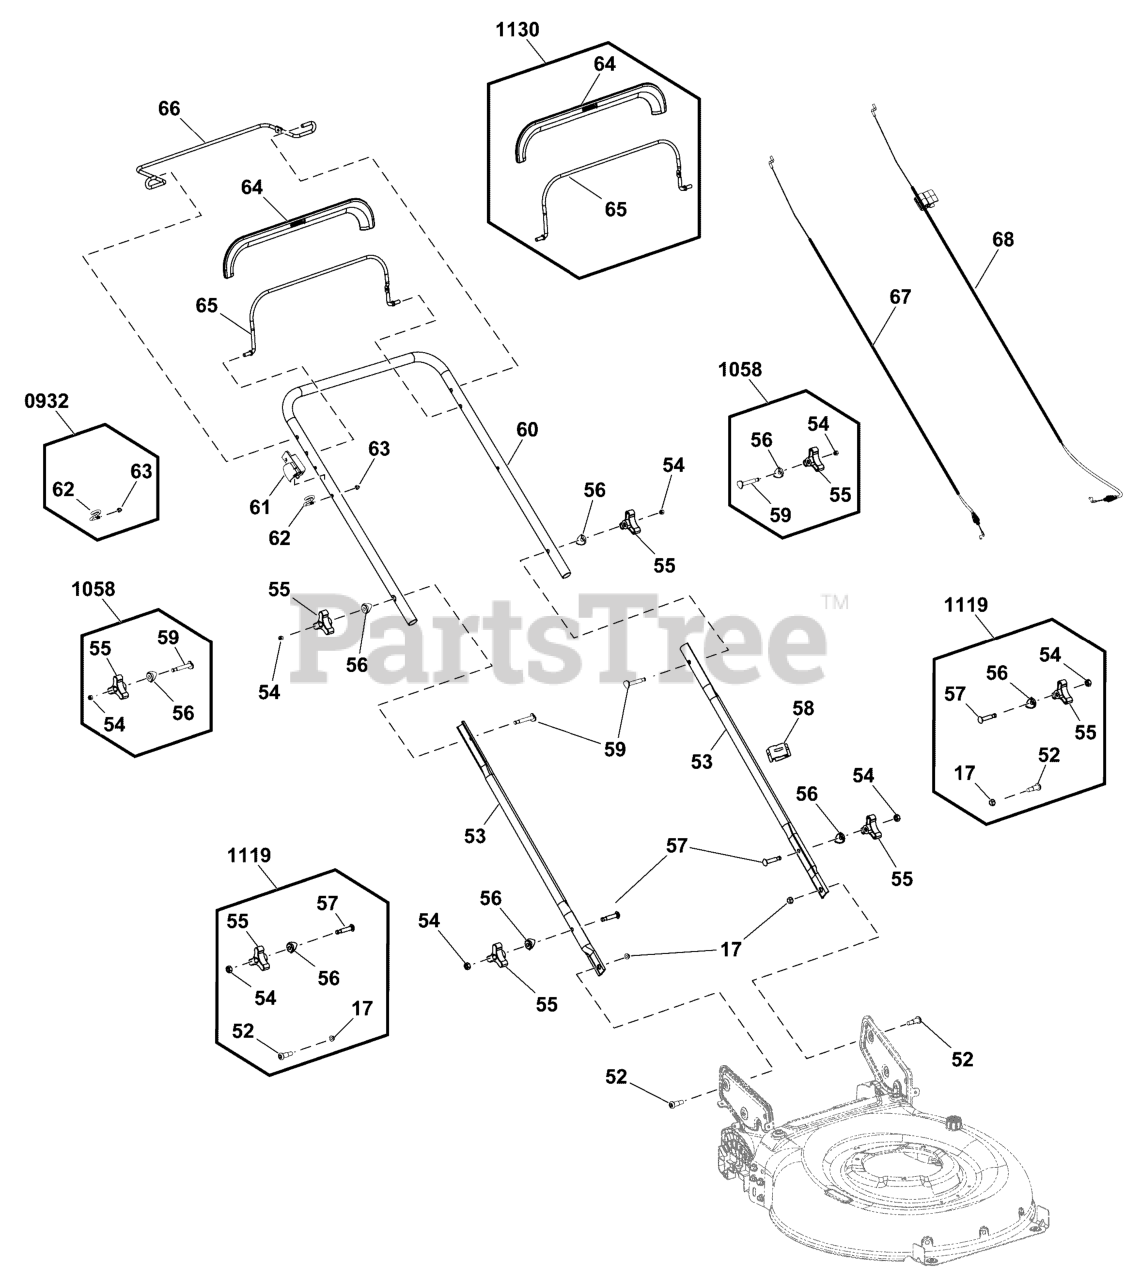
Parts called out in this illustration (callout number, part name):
17	NUT, Lock
52	BOLT
53	HANDLE, Lower
54	NUT
55	KNOB, Wing
56	WASHER, Curved
57	BOLT
58	CLAMP, Wire
59	BOLT, Carriage
60	HANDLE, Upper
61	BRACKET, Rod
62	GUIDE, Rope
63	NUT, Lock
64	COVER
65	BAIL ASSEMBLY
66	BAIL ASSEMBLY
67	CABLE, Drive
68	CABLE, Engine Stop
0932	KIT, Rope Guide
1058	KIT, Wing Knob, Handle
1119	KIT, Wing Knob, Handle
1130	BAIL ASSEMBLY
